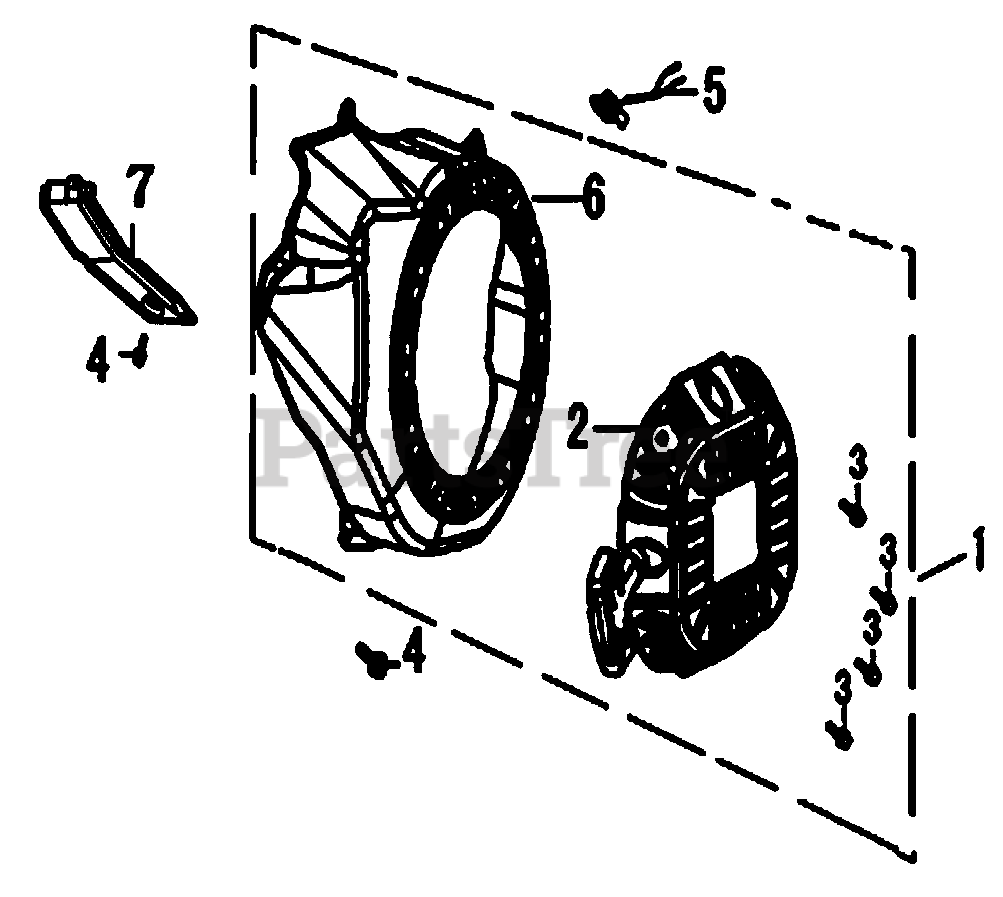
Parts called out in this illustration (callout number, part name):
1	RECOIL STARTER W/HSNG
2	STARTER ASSY., RECOIL
3	BOLT, FLANGE 6x8
4	BOLT, FLANGE 6x12
5	SWITCH ASSY., ENGINE STOP
6	HOUSING, BLOWER
